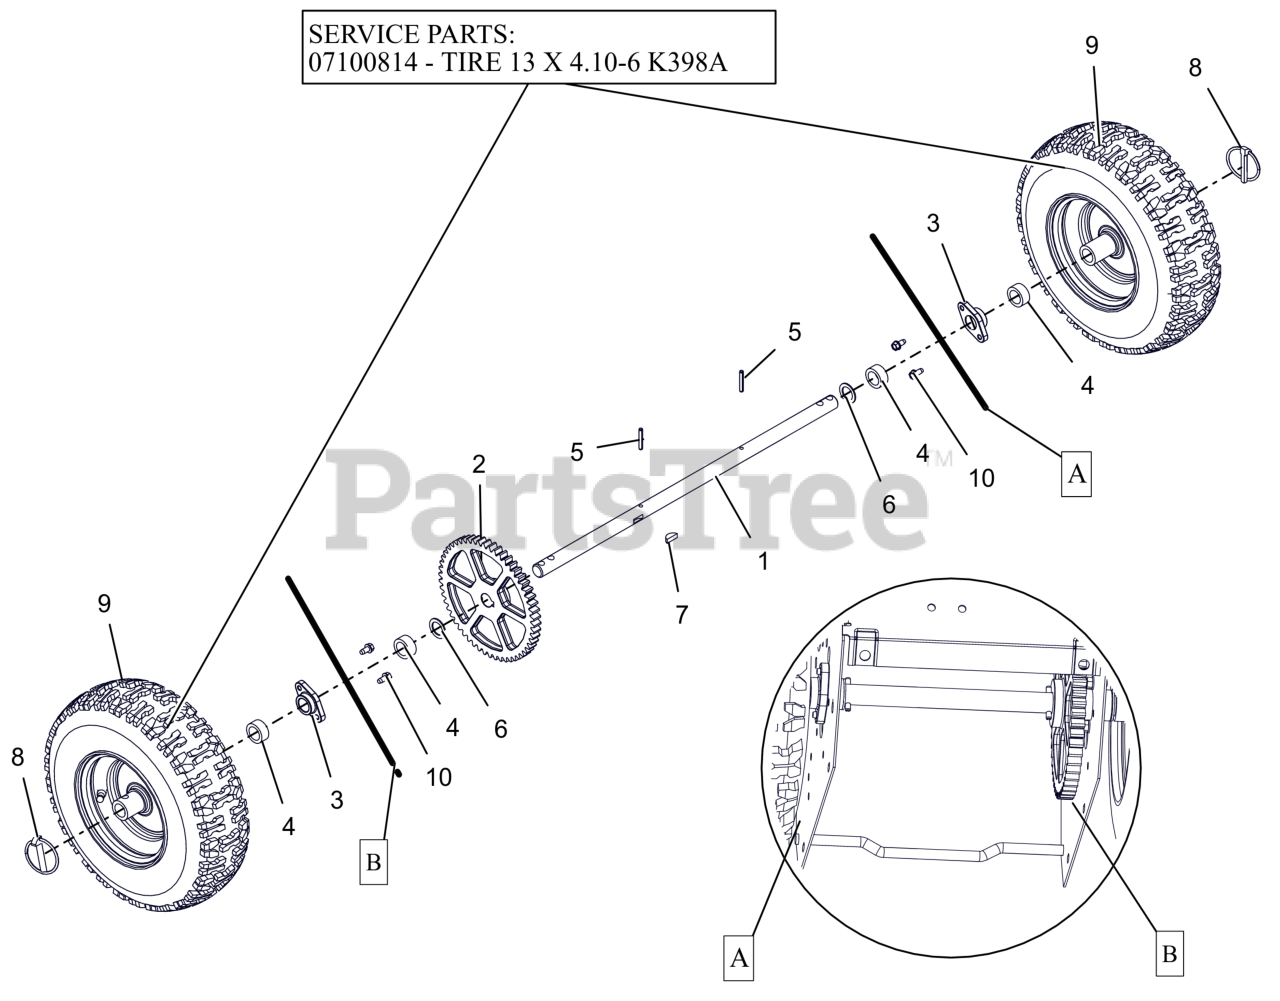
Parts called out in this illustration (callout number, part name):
1	AXLE, COMPACT
2	SPUR GEAR, 54T .75ID X 6.75PD
3	BSHG .75X1.125X.65
4	BSHG-SLV .766 X 1.125 X .500
5	PIN-ROLL .188X1.25
6	WSHR, FLT .754X1.125X.062 ZCC
7	KEY-WDRF .25X.750X.313 SAE91
8	PIN-LOK .31X1.75
9	TIRE/WHEEL, 13X4.10-6
9	TIRE, 13" K398A
9	TUBE
10	SCR-TAP .25-20X.50 HWH ZCC
